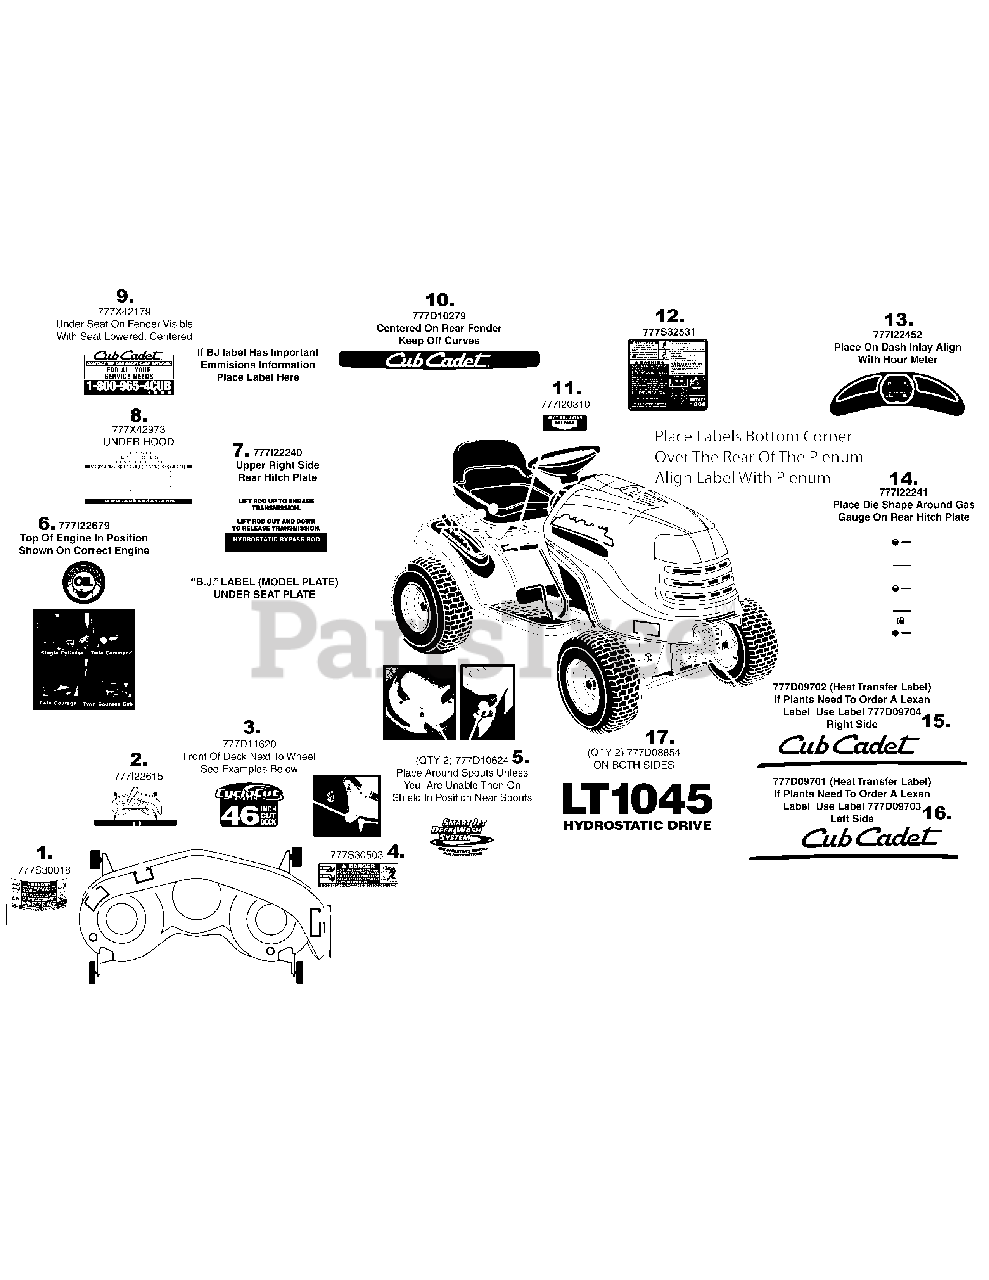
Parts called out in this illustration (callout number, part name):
1	LABEL-DECK SAFETY
2	LABEL-BELT ROUTE
3	LABEL-CYCLO CUT 46" BLUE
4	LABEL-DANGER CHUTE
5	LABEL-RIDER:DECK WASH CUB
6	LABEL-CHECK ENG OIL
7	LABEL-HYDRO ENGAGE
8	LABEL-PARTS LIST LT1045
9	LABEL-CUB HOTLINE
10	LABEL-REAR FENDER
11	LABEL-SEAT ADJUSTE
12	LABEL-FRAME COVER
13	LABEL-DASH PANEL
14	LABEL-FUEL LEVEL
15	LABEL-RGT SIDE HOOD
16	LABEL-LFT SIDE HOOD
17	LABEL-MODEL LT1045
